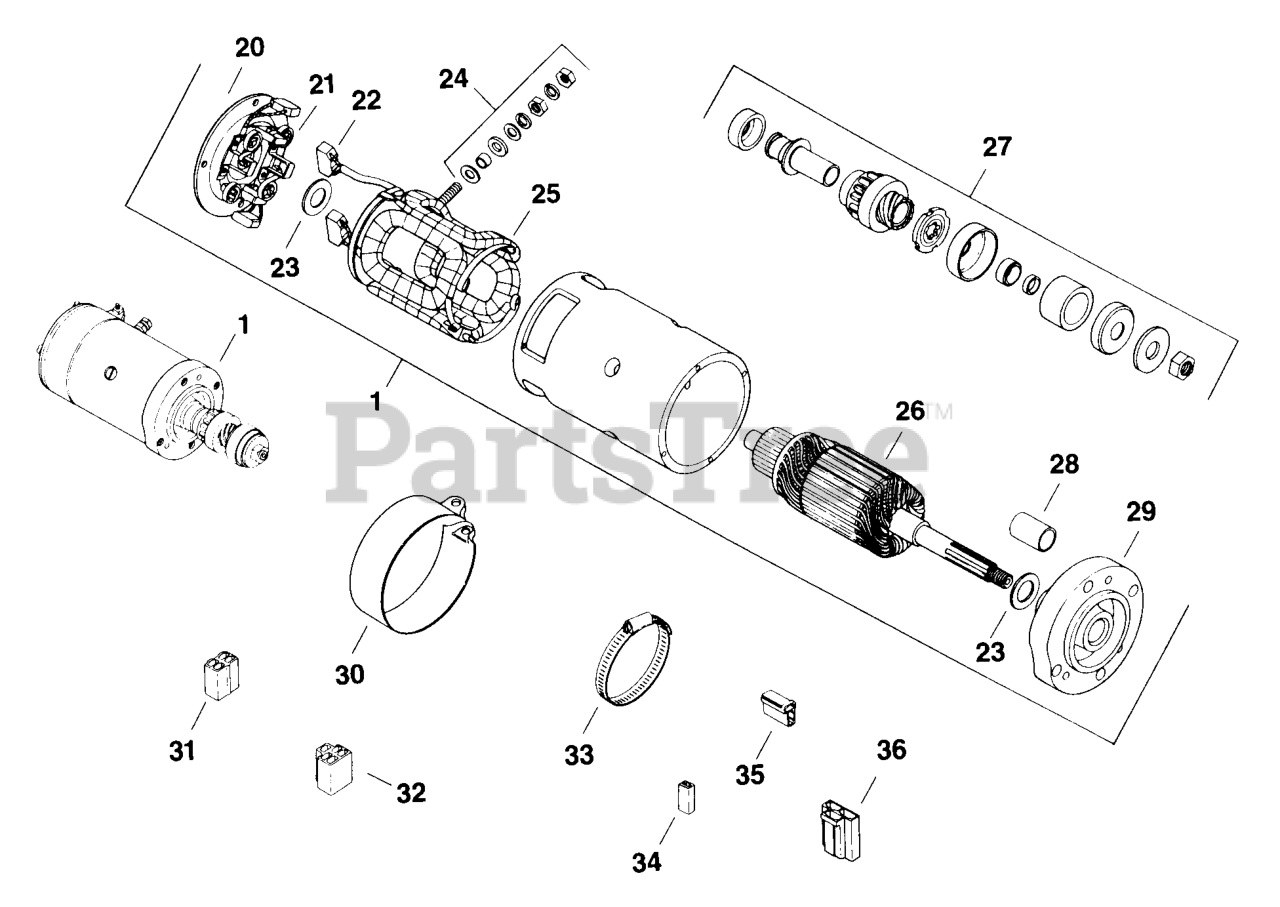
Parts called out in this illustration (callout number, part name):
1	KIT, STARTER - DISCONTINUED
20	HEAD - DISCONTINUED
21	SPRING - DISCONTINUED
22	BRUSH - DISCONTINUED
24	STUD - DISCONTINUED
25	COIL - DISCONTINUED
26	ARMATURE - DISCONTINUED
27	KIT - USE A-277214-S
28	BEARING - DISCONTINUED
30	BAND - DISCONTINUED
33	CLAMP - DISCONTINUED
A-277214-S	KIT, STARTER - DISCONTINUED
